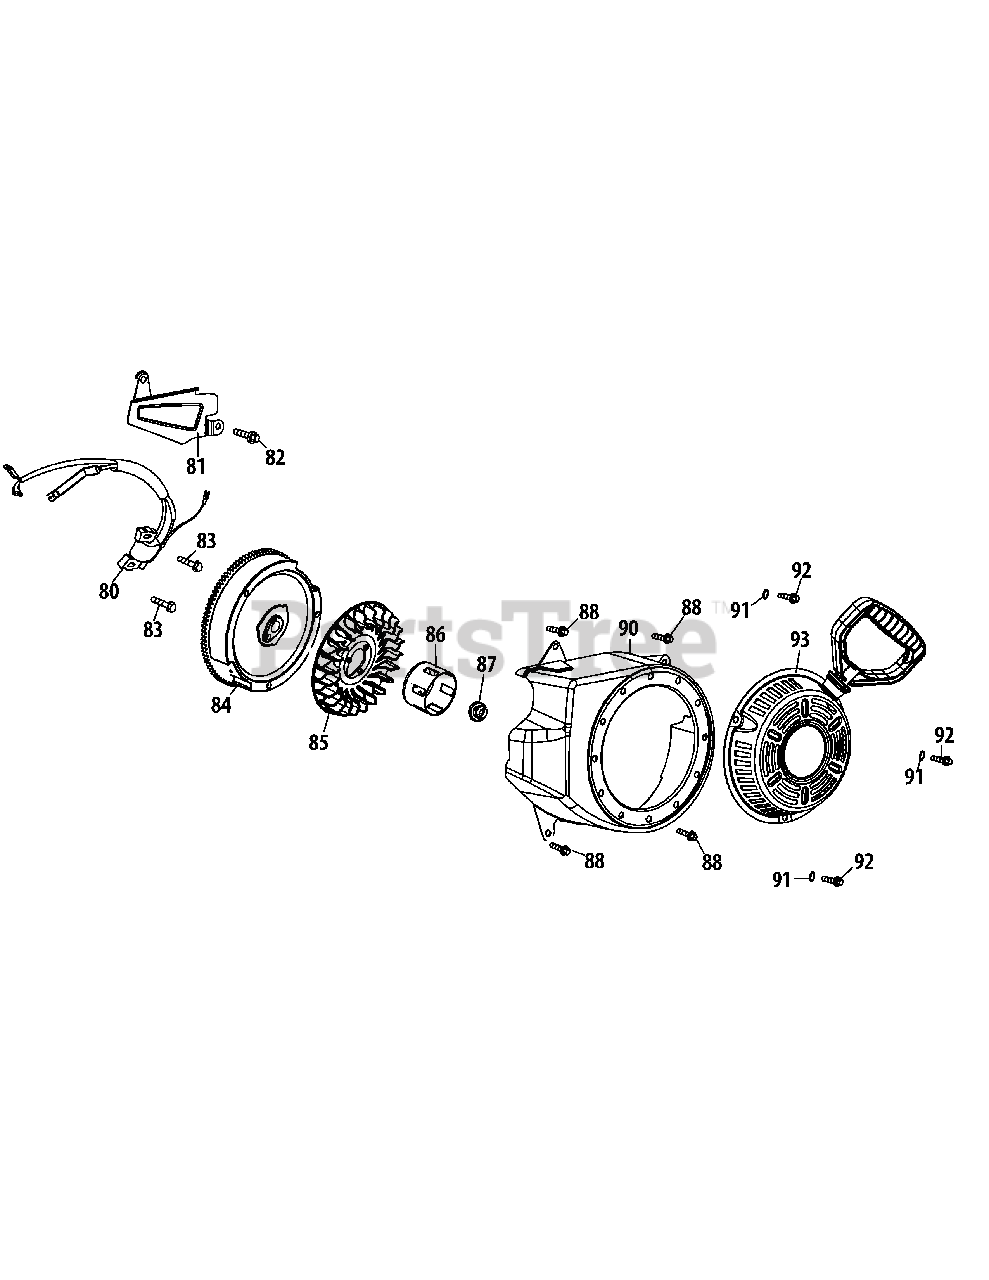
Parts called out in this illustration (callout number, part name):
80	Ignition Coil
81	Shield - Air Flow
83	Bolt - Flange M6
84	Flywheel
85	Cooling Fan
86	Starter Cup
87	Nut - M14
88	Bolt - M6 X 12 Zin
90	Fan Cover Complete
91	Flat Washer-Recoil
92	Flange Bolt M6
93	Recoil Start Assembly
